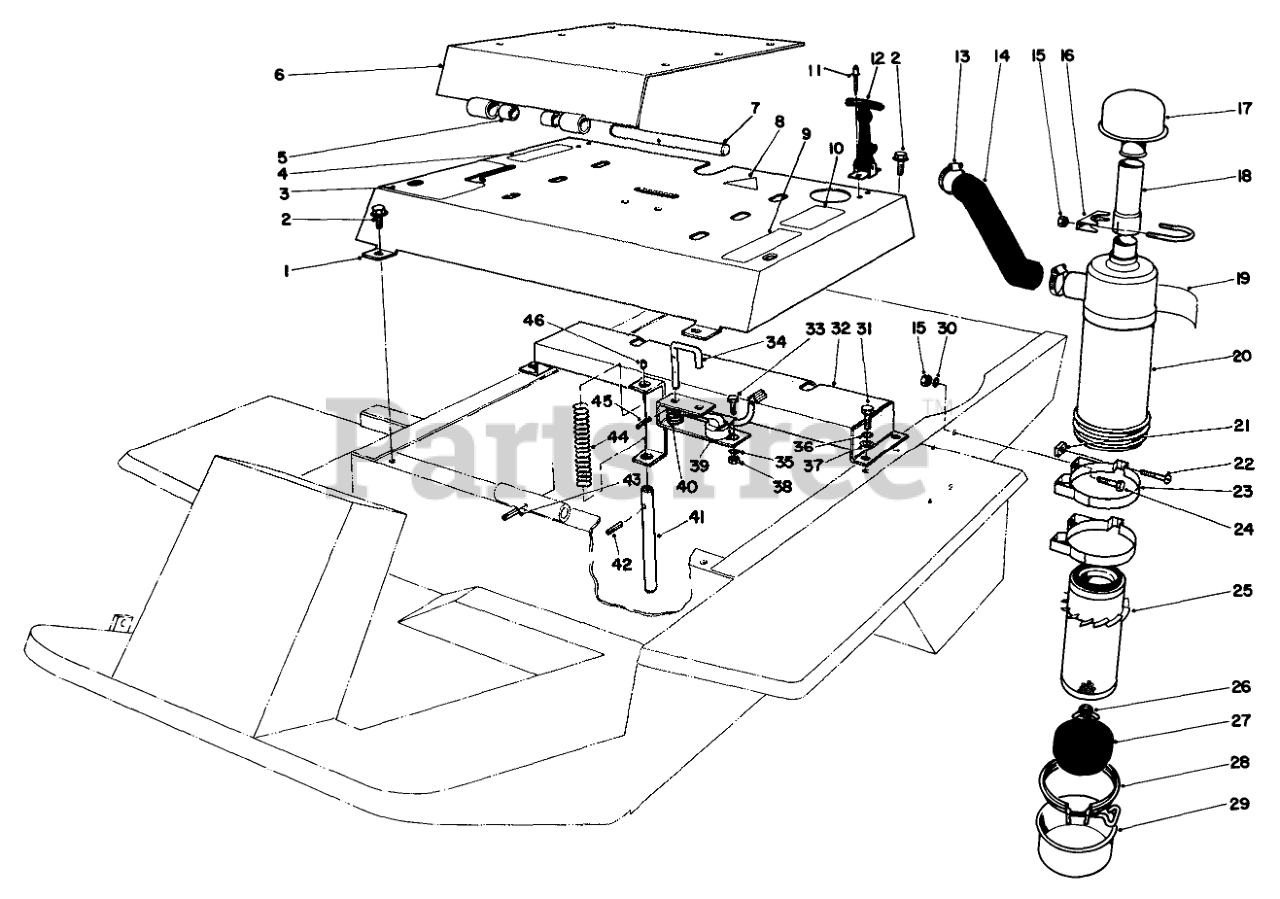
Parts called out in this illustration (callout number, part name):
1	Cover-Seat Support (Incl. Ref. #4, 5, 9 & 10)
2	SCREW-HHFTF
3	DECAL - LIFT CONTROL
4	DECAL-WARNING
5	.503ID X .875LG BSHG
6	Seat Mounting (Incl. Ref. #5)
7	SHAFT-PIVOT, SEAT
8	DECAL-DANGER
9	DECAL - CAUTION
10	DECAL-REFUELING
11	RIVET
12	Assembly-Handle
13	CLAMP-HOSE
15	NUT-HEX
16	CLAMP-MUFFLER
18	Tube-Air Cleaner
19	DECAL-INSTALLATION
20	Air Cleaner Assembly (Incl. Ref. #18 & 24-28)
21	NUT-SQUARE
22	SCREW
23	Band Assembly Mounting (Incl. Ref. #20 & 21)
24	SCREW-HH
25	ELEMENT ASM
26	NUT AND GASKET ASM
27	SKIRT-BAFFLE
28	CLAMP ASM
29	A/C CUP ASM
30	WASHER-LOCK
31	SCREW-HH
32	Seat Support
33	SCREW-HH
34	SEAT SWITCH PIN
35	WASHER-LOCK
36	WASHER-LOCK
37	WASHER-FLAT
38	NUT-HEX
39	SWITCH ARM
40	SPRING
41	PIN-SWITCH, SEAT
42	PIN-ROLL, SLOTTED
43	PIN-ROLL, SLOTTED
44	SPRING-COMP
45	PIN-ROLL, SLOT
46	PIN-PEDAL
